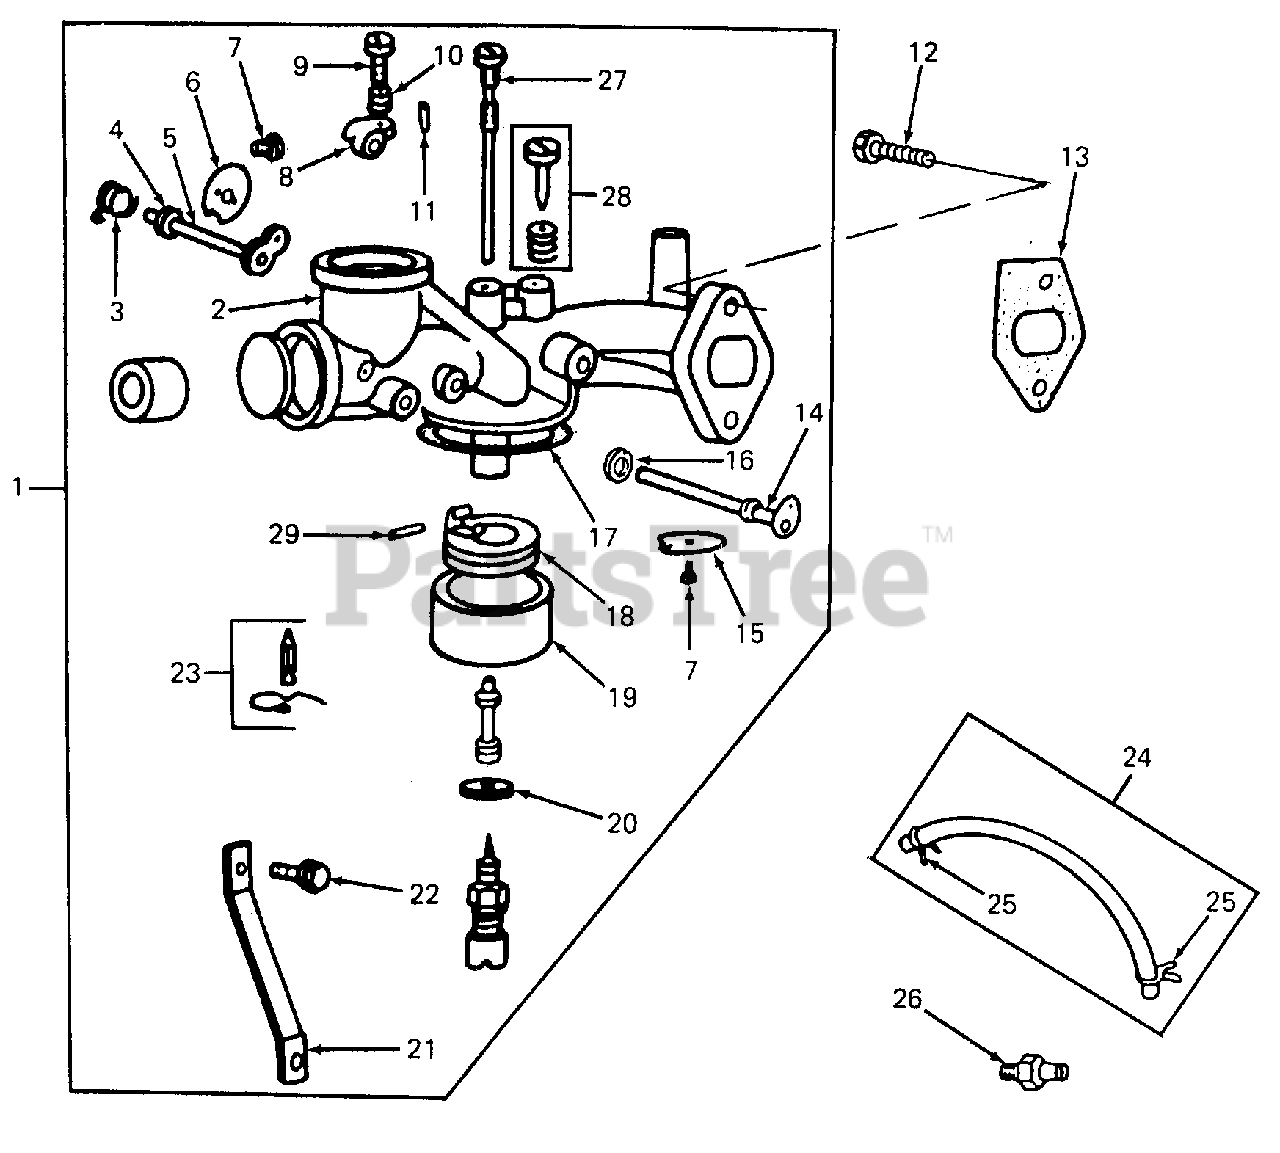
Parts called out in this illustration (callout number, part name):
1	Carburetor Assembly
2	Body Assembly
3	Spring, Choke Return
4	Washer, Choke Shaft
5	Shaft & Lever, Choke
6	Valve, Choke
7	Screw, Throttle & Choke Valve Mtg Stem
8	Stop, Throttle
9	Screw, Machine Fill Hd 8-32 X 5/8
10	Spring, Throttle Adjustment
11	Pin, Throttle Stop
12	Screw, Carburetor Mtg
13	Gasket, Carburetor Mtg
14	Shaft & Lever, Throttle
15	Valve, Throttle
16	Lip, Seal
17	Gasket, Float Bowl
18	Float, Carburetor
19	Float, Bowl
20	Washer, Float Bowl
21	Bracket, Carburetor
22	Screw, Bracket Carburetor
23	Valve, Fuel Inlet
24	Line, Vent (Includes Ref No. 25 [2])
25	Clamp, Line Vent
26	Connector, Fuel Pipe
27	Carburetor Nozzle
28	Idle Valve Assy
